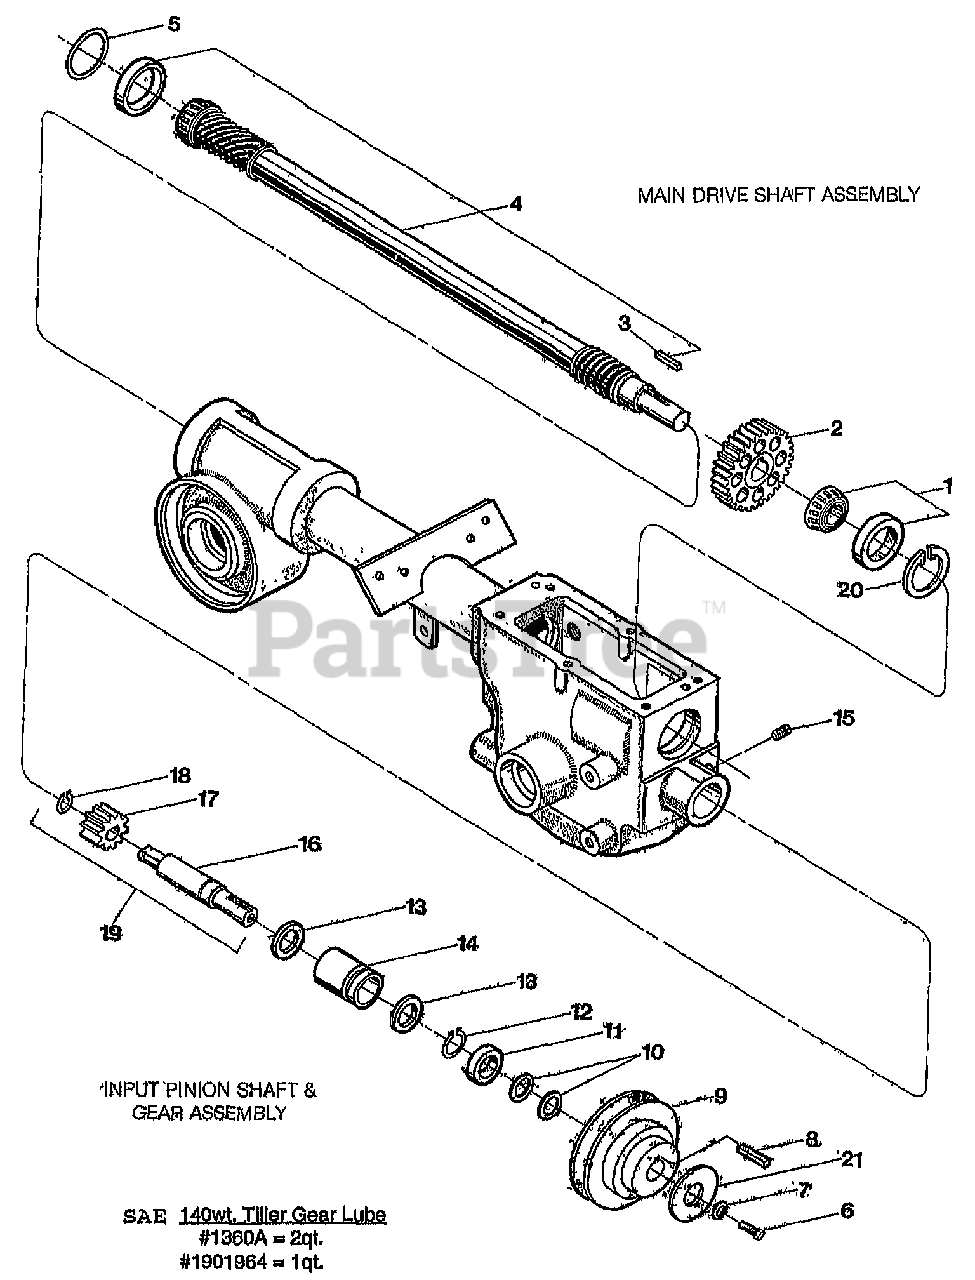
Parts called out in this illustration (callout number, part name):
1	KIT-BRG CONE&RACE-DRIVESHAFT (FRT OF DRIVE SHAFT)
2	GEAR-SPUR 30 TEETH
3	KEY-.188 SQX1.0
4	KIT-DRIVESHAFT
5	SHIM-1.75X1.5X.01
5	SHIM-1.75X1.5X.03
5	SHIM-1.75X1.5X.005
6	SCR-HH 5/16-24X.75 G5 ZP
7	WASHER-.827X.331X.098 (CONCAVE SURFACE FACES PULLEY)
8	KEY-.188 SQX1.0
9	PULLEY-TRANS MACH
10	WASHER # .875 X .65 X .06
11	SEAL-PINION SHAFT PT/85030/00
12	RING-RETAIN EXT .707 ID (SNAP RING)
13	WASHER-1.022X.752X .059
14	BUSHING-1.24X.75X1.8 GRVD
15	SCR-SS 5/16-18X.375
16	SHAFT-PINION(P-V)
17	GEAR-PINION P/M
18	RING-BOWED EXT .461 ID
19	PINION W/GEAR&SNAP RING (INCL. 16-18)
20	RING-RETAINING 5000-181
21	WASHER-2.5X.316X.06
